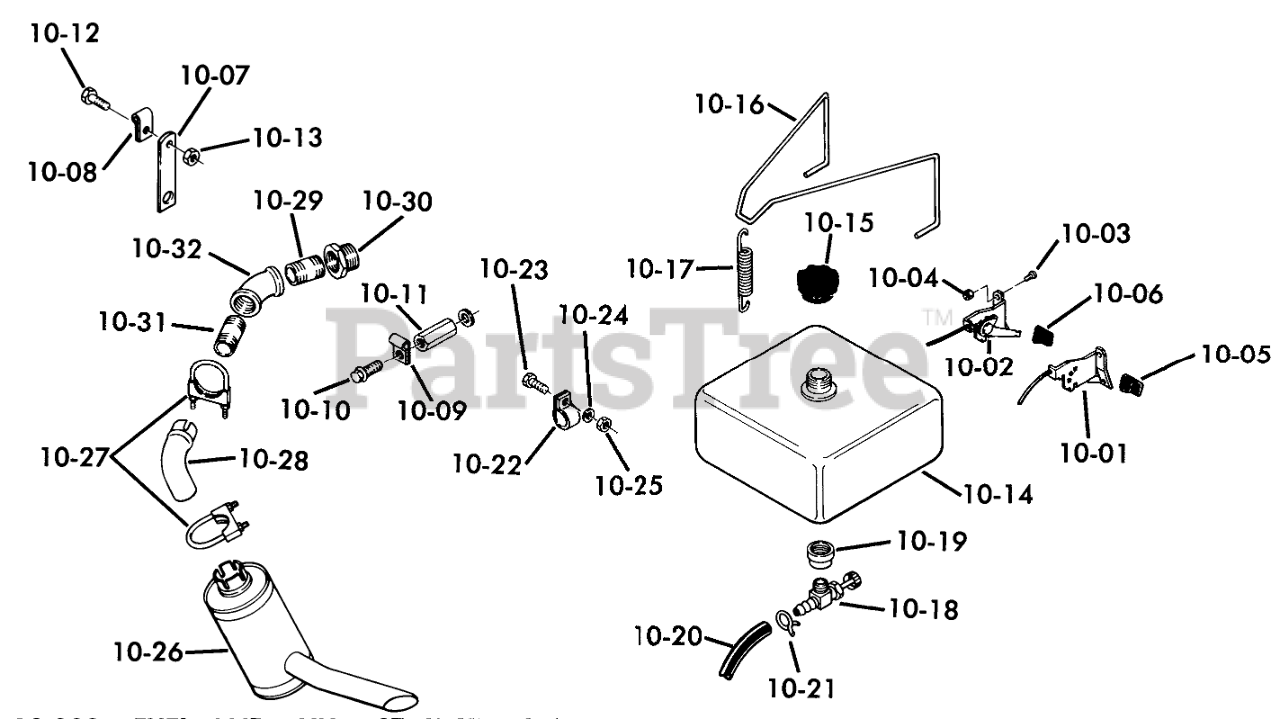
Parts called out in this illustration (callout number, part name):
10-01	Choke Control
10-02	THROTTLE CONTROL
10-03	SCREW
10-04	#10-24 Kep-Nut
10-05	KNOB-CHOKE
10-06	KNOB-THROTTLE
10-07	Strap
10-08	THROTTLE CONTROL CLP
10-09	Clip
10-10	Screw
10-11	Special Nut
10-12	Screw
10-13	Nut
10-14	ASSY-FUEL TANK
10-15	Cap
10-16	HOLD DOWN WIRE
10-17	CLUTCH SPRING
10-18	VALVE-FUEL
10-19	BUSHING
10-20	Fuel Hose
10-21	Clamp
10-22	CLAMP-HOSE
10-23	Bolt
10-24	WASHER 5/16 SAE
10-25	Nut
10-26	MUFFLER
10-27	ASSY-MUFFLER CLAMP
10-28	MUFFLER INLET TUBE
10-29	NIPPLE
10-30	REDUCER 1 1/4-1
10-31	Nipple 1" Pipe
10-32	ELBOW
